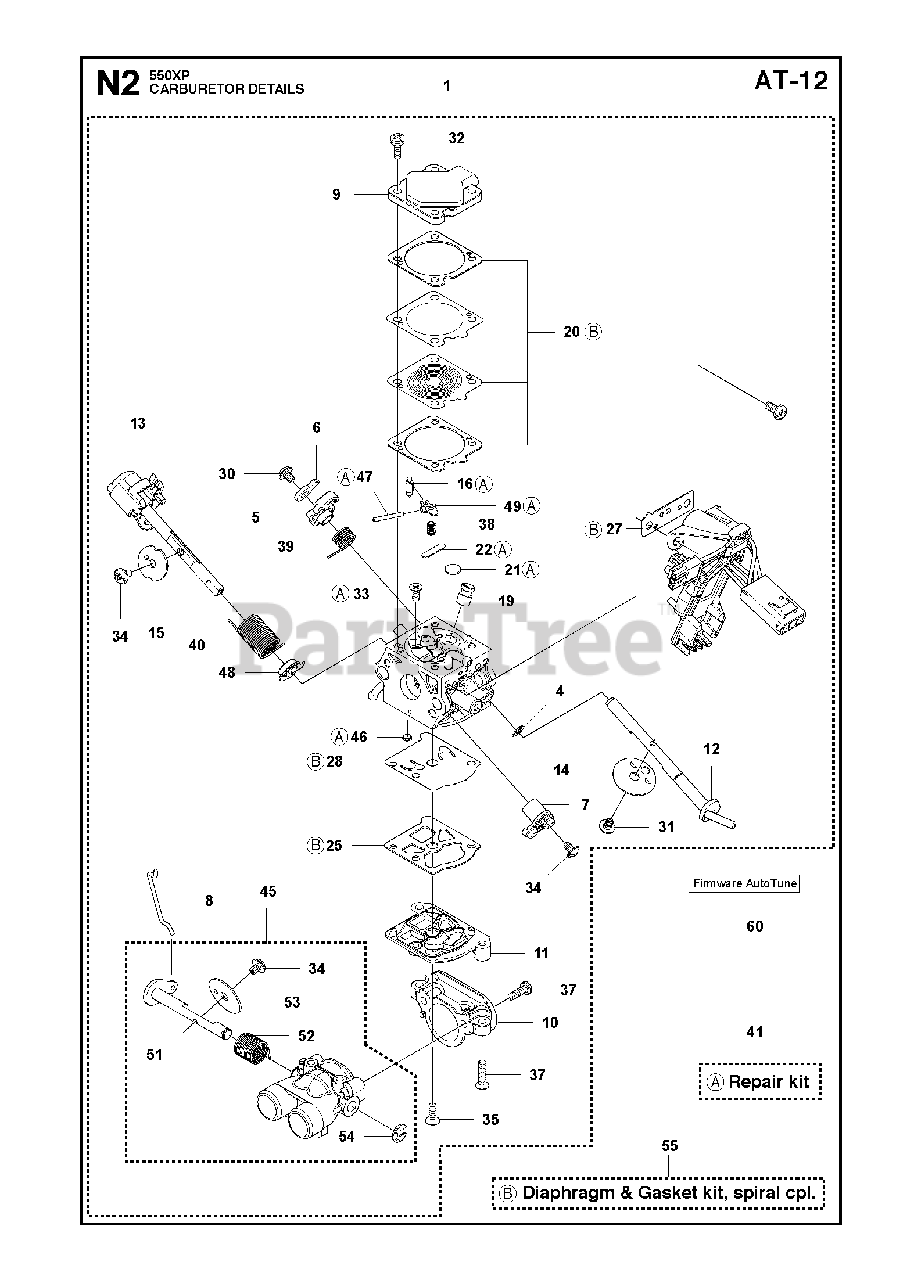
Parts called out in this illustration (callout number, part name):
1	CARBURETTOR KIT
4	RETAINER
5	LEVER
6	LEVER
7	THROTTLE LEVER ASSY
8	LINK
9	COVER
10	INLET
11	COVER
12	SHAFT ASSY
13	SHAFT
14	VALVE
15	VALVE
16	INLET NEEDLE
19	NOZZLE ASSY
20	DIAPHRAGM & GASKET KIT AT SPIR
21	PLUG WELCH
22	Lever
25	GASKET
27	GASKET
28	DIAPHRAGM
30	SCREW
31	SCREW
32	SCREW
33	SCREW
34	SCREW
35	SCREW
37	SCREW
38	SPRING
39	SPRING
40	SPRING
41	GASKET KIT
45	THROTTLE VALVE ASSY
46	FUEL INLET SCREEN
47	FULCRUM PIN
48	BUSHING
49	PLUG
51	SHAFT ASSY AIR THROTTLE
52	SPRING
53	VALVE
54	E CLIP
55	DIAPHRAGM & GASKET KIT AT SPIR
60	Husqvarna TBD
